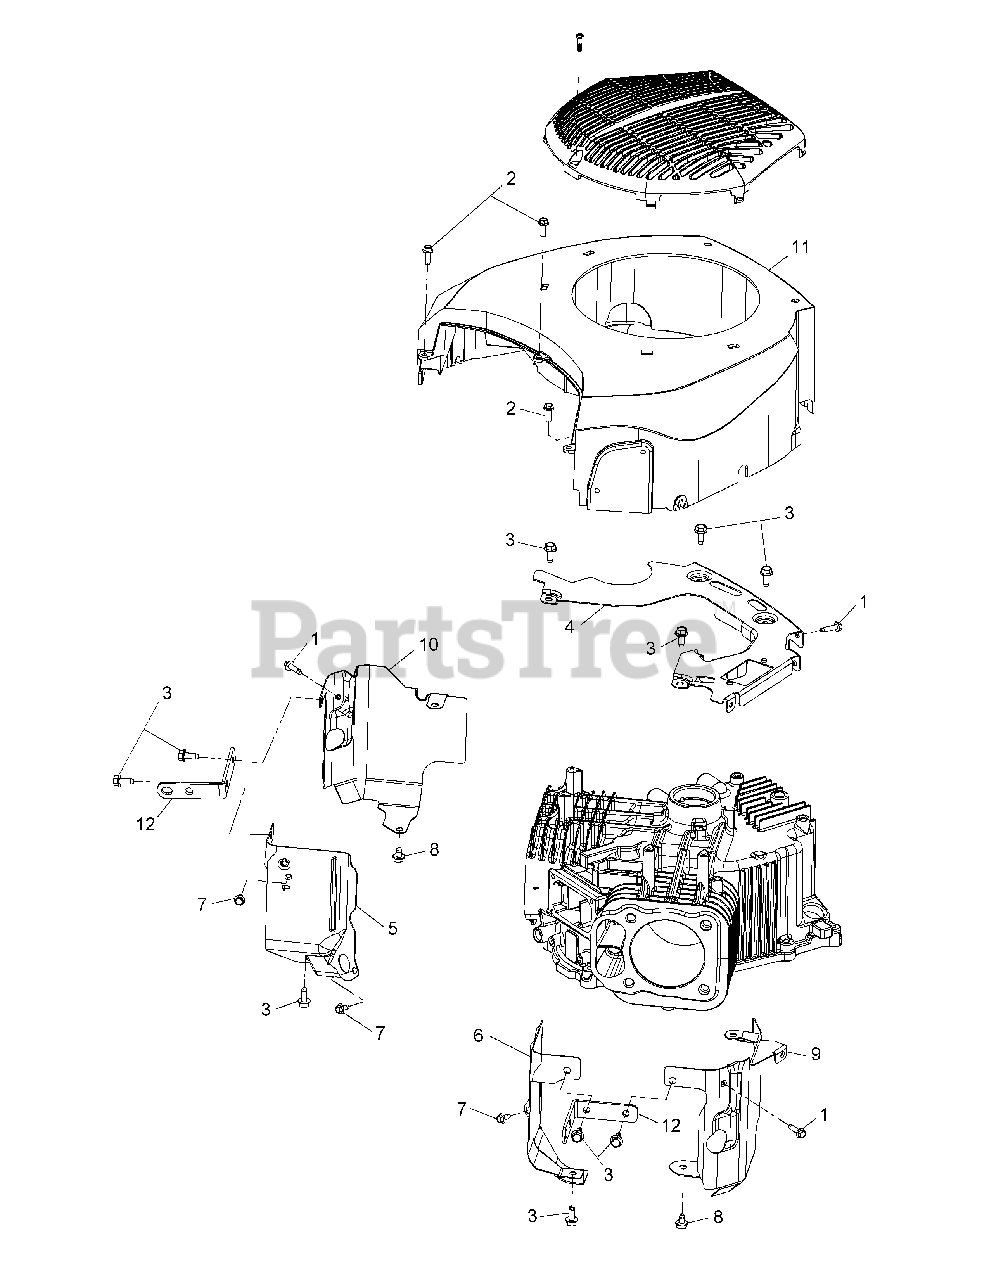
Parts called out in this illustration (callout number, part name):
1	Thread Forming Screw
3	Thread Forming Screw
4	Backing Plate
5	Valley Baffle, #1 Cylinder
6	Valley Baffle, #2 Cylinder
7	Thread Forming Screw
8	Thread Forming Screw
9	Left Barrel Baffle
10	Right Barrel Baffle
11	Blower Housing
